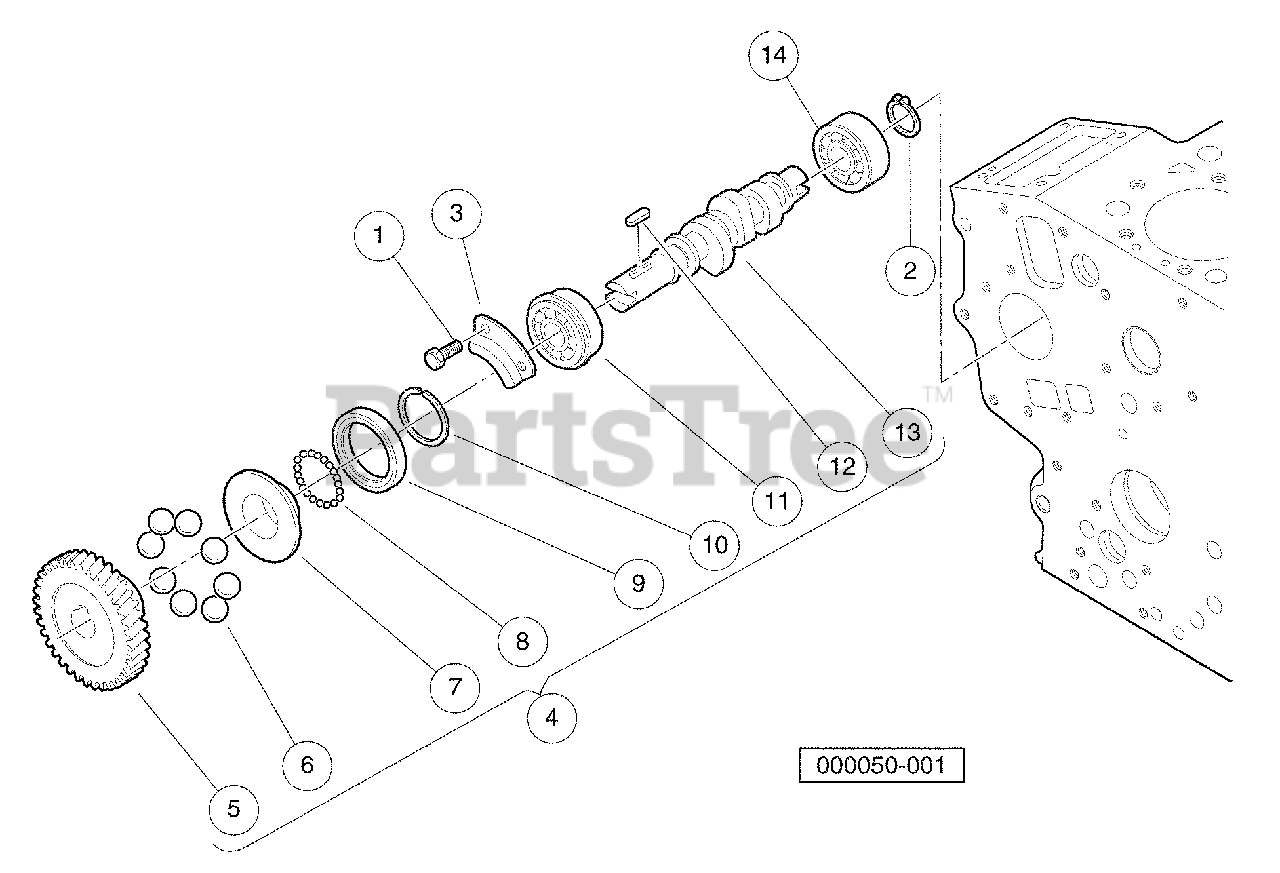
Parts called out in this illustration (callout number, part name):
1	Bolt, D722, Cam End
2	Circlip, External
3	Stopper, Fuel, C/shaft
4	Assy, Fuel Camshaft
5	Gear, Injection Pump
6	Ball, Injection Pump
7	Sleeve, Governor
8	Ball, Governor
9	Case, Governor Ball
11	Bearing, Ball
12	Key, Feather, Short Camshaft.
13	Camshaft, Fuel, Short
14	Bearing, Ball
